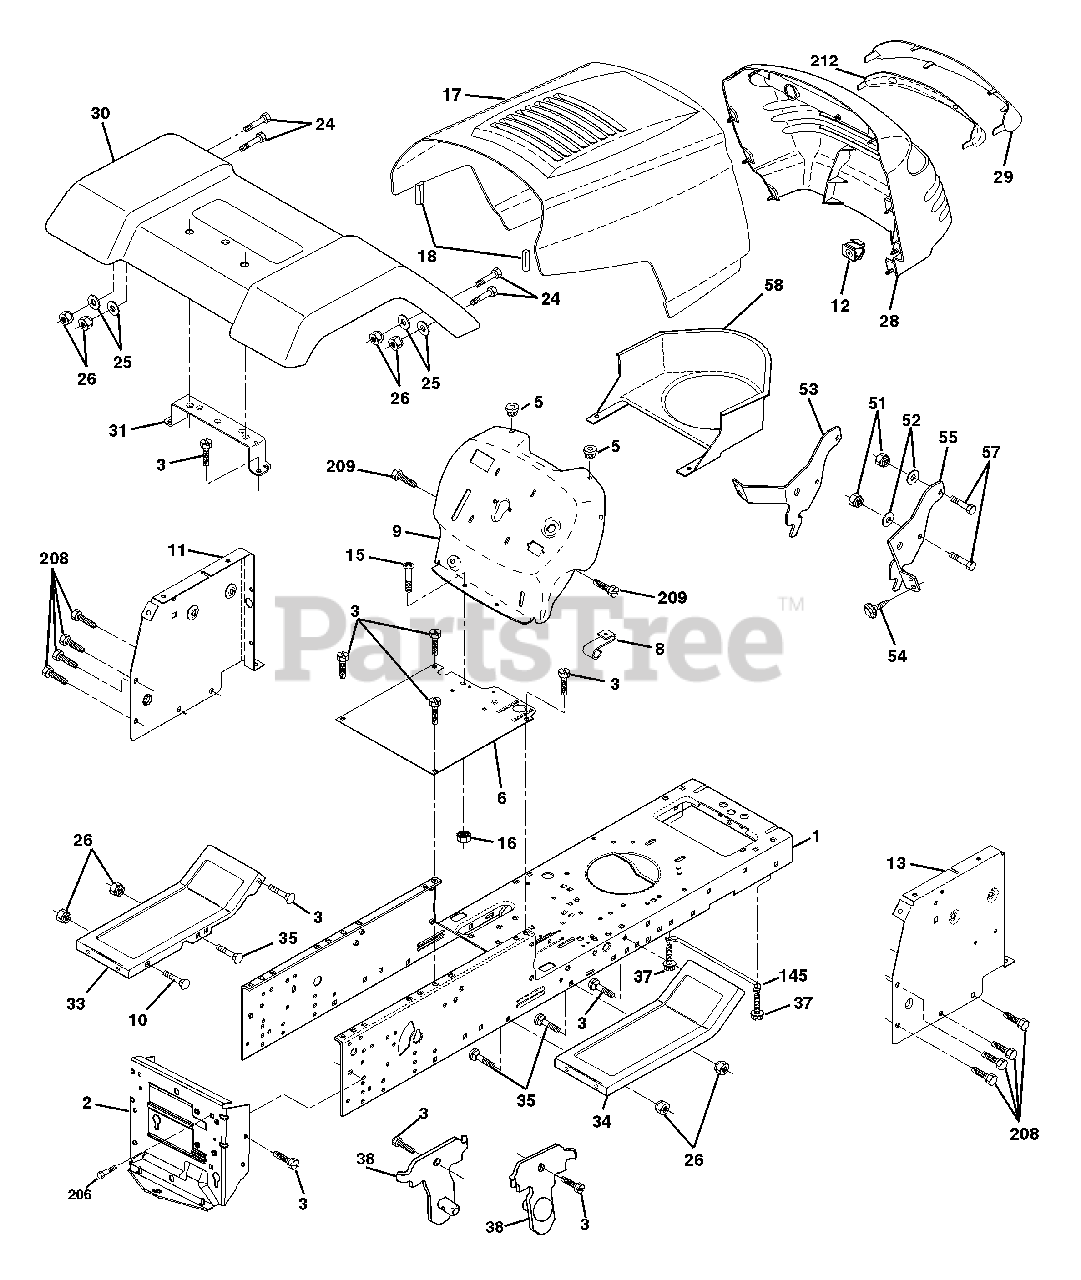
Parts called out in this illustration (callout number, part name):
2	Drawbar
3	Screw 3/8-16 x 3/4
5	Bumper Hood/Dash
6	Saddle Flat Lt
8	Clip Retainer Slide-On
9	Dash
10	Bolt Rd Hd Sqnk. 3/8-16 Unc x 1
11	Panel Asm. Dash Lh
12	Clip Tinnerman Grile P/L
15	Screw Mach Trhd 5/16-18 Unc x 3/4
16	Nut Keps 5/16-18 Unc
17	Hood
18	Bumper Hood
24	Bolt Fin Hex 3/8-16 Unc x 1 Gr. 5
25	Washer 13/32 x 13/16 x 12 Ga.
26	Nut Lock Hex w/Insert 3/8-16 UNC
28	Grill/Lens Asm
29	Lens Grille Private label
30	Fender Asm
31	Bracket Fender
33	Footrest Lh
34	Footrest Rh
35	Bolt Rd Hd Sht. Sqnk. 3/8-16 x 3/4
37	Screw Thdrol 5/16-18 x 1/2 Tyt
38	Bracket Asm. Pivot Mower Rear
51	Nut Lock Hex W/Ins. 1/4-20
52	Washer 9/32 x 7/8 x 16 Ga.
53	Bracket Grille LH
54	Screw Hex Wshd 8-18 x 7/8
55	Bracket, Grille RH
57	Bolt Fin Hex 1/4-20 x .75
58	Air Duct Private Label
145	Rod Pivot Chassis/Hood
206	Bolt shoulder 5/16-18
208	Screw Thdrol 3/8-16 x 1/2
209	Screw Hex Wsh Thdrol 3/8-16
212	Insert Lens Reflector
